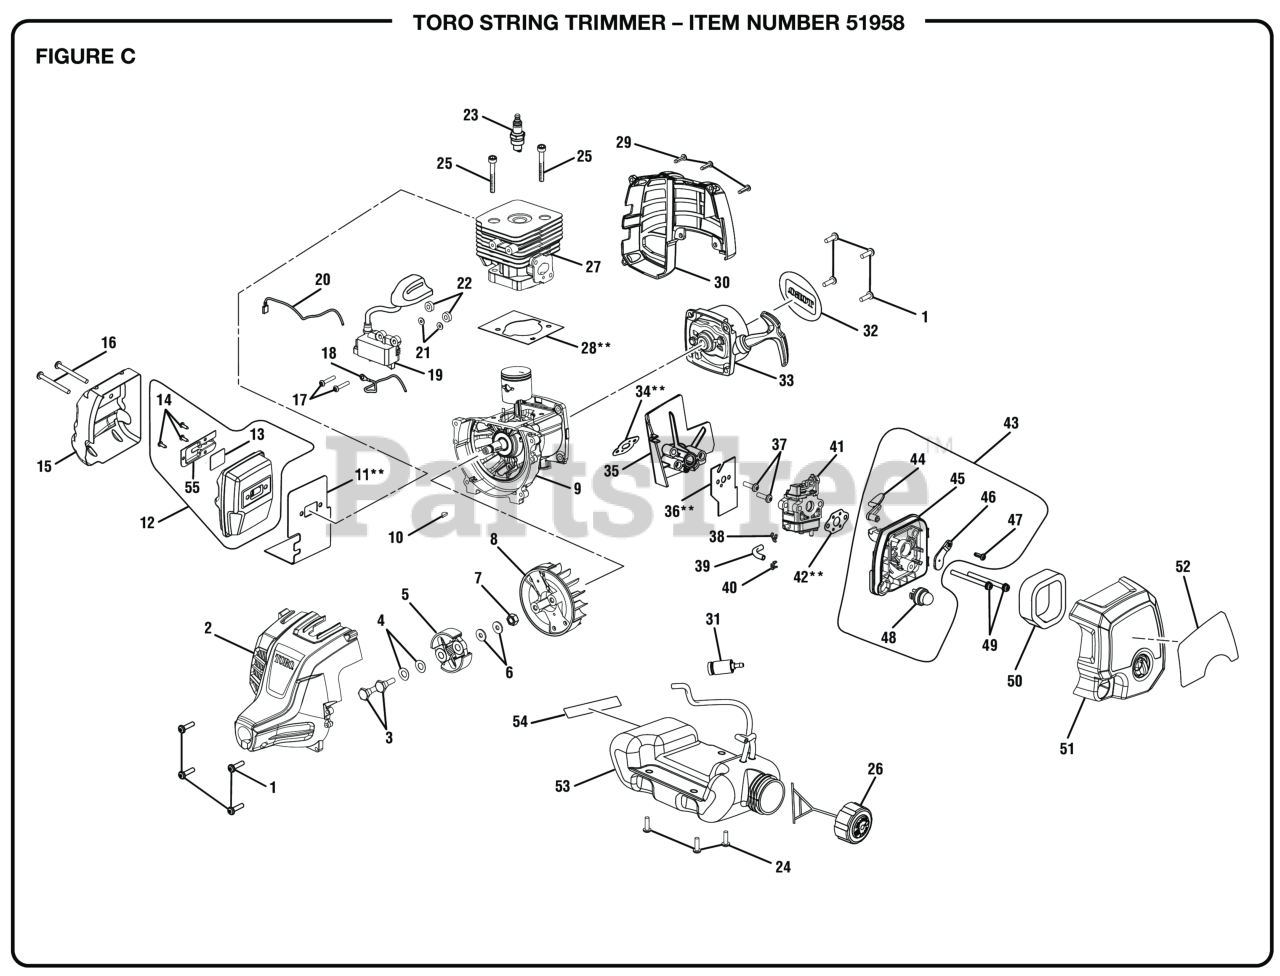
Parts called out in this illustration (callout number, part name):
1	Cap Screw w/Washer (M5 x 16 mm, T25 Torx Soc. Hd.)
2	Front Housing Assembly
3	Clutch Shoulder Bolt (M6 x 22.5 mm, Hex Hd.)
4	Washer (Curved)
5	Clutch Assembly
6	Washer (ID6 x OD15 x 1.2t)
7	Flange Nut (M8, Flywheel)
9	Crankcase Assembly.
10	WOODRUFF KEY (10 mm X 3 mm)
11	Muffler Gasket
12	Muffler Assembly
13	SCREEN
14	Screw (6-20 x 1/4 in., T20 Torx Pan Hd. S.T.)
15	HEAT SHIELD
16	Screw (M5 x 50 mm, Torx Slotted Recessed Pan Hd.)
17	Screw (M4 x 22 mm, T20 Torx Slotted Recessed Pan Hd.)
18	Lead Wire Assembly, Red
19	Coil Boot Assembly
20	Lead Wire Assembly, Black
21	Flat Washer (OD10 x ID42 x 1t)
22	Phenolic Spacer (Ignition Module)
23	SPARK PLUG (CHAMPION RCJ4)
24	Shoulder Screw w/Washer (M4 x 14 mm, T25 Torx Truss Hd.)
25	Screw (M5 x 22 mm, T25 Torx Soc. Hd.)
26	Fuel Cap Assembly
28	Gasket
29	Screw (M4 x 18 mm, T20 Torx Pan Hd. S.T.)
30	Rear Engine Housing
31	Fuel Filter
32	Logo Label (Rear)
33	Starter Recoil & Starter Cup Assembly
34	Heat Dam Insulator
36	Gasket
37	Screw w/Washers (M5 x 30 mm, T25 Torx Pan Hd.)
38	Clip-hose (Id 4.9)
39	Fuel Line (45 mm)
40	CLIP-HOSE (ID 4.9)
41	CARBURETOR ASSEMBLY
42	Carburetor Gasket
43	Filter Housing Assembly
44	CHOKE LEVER
45	CARBURETOR PLATE
46	Screw (M4 x 12 mm, T20 Torx Pan Hd. S.T.)
47	Screw (M4 x 12 mm, Slotted Recessed Pan Hd.)
48	Primer Bulb Assembly
49	Screw (M5 x 44 mm,T25 Torx Hd. Carburetor)
50	Air Filter (Element)
51	Airbox Cover Assembly w/Label
52	Starting Instructions Label
53	Fuel Tank & Cap Assembly
54	Combustion Warning Label
55	Trimmer Outlet
